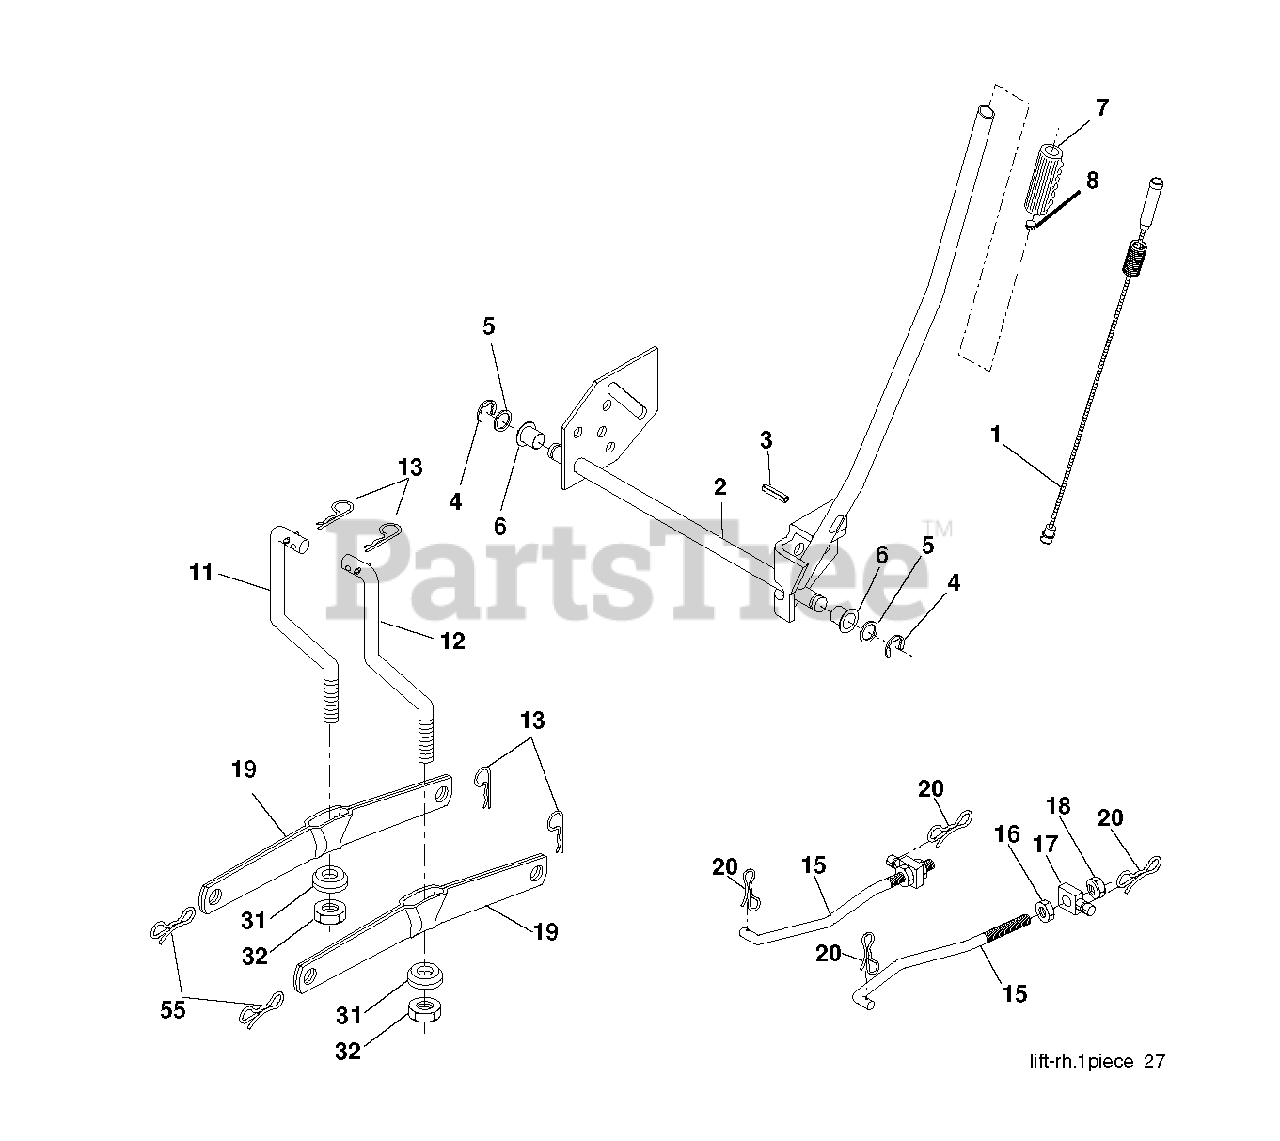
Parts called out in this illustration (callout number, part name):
1	PLUNGER.ASM.LIFT.LVR.BLK.17.32
2	SHAFT ASM R HANDLE
4	RETAINING RING LT
6	BEARING.NYLON
7	GRIP
8	PLUNGER BUT KIT
11	LINK LIFT LH
12	LINK LIFT RH
13	RETAINER-SPRNG RB
15	LINK.SUSPENSION.FRONT
16	NUT
18	NUT
19	ARM.REAR.SUSPENSION
20	PIN.COTTER.7/16.BOW TI
31	BEARING.PIVOT.LIFT
32	NUT CROWNLOCK 3/8-24
55	PIN.COTTER.5/16.BOW TI
